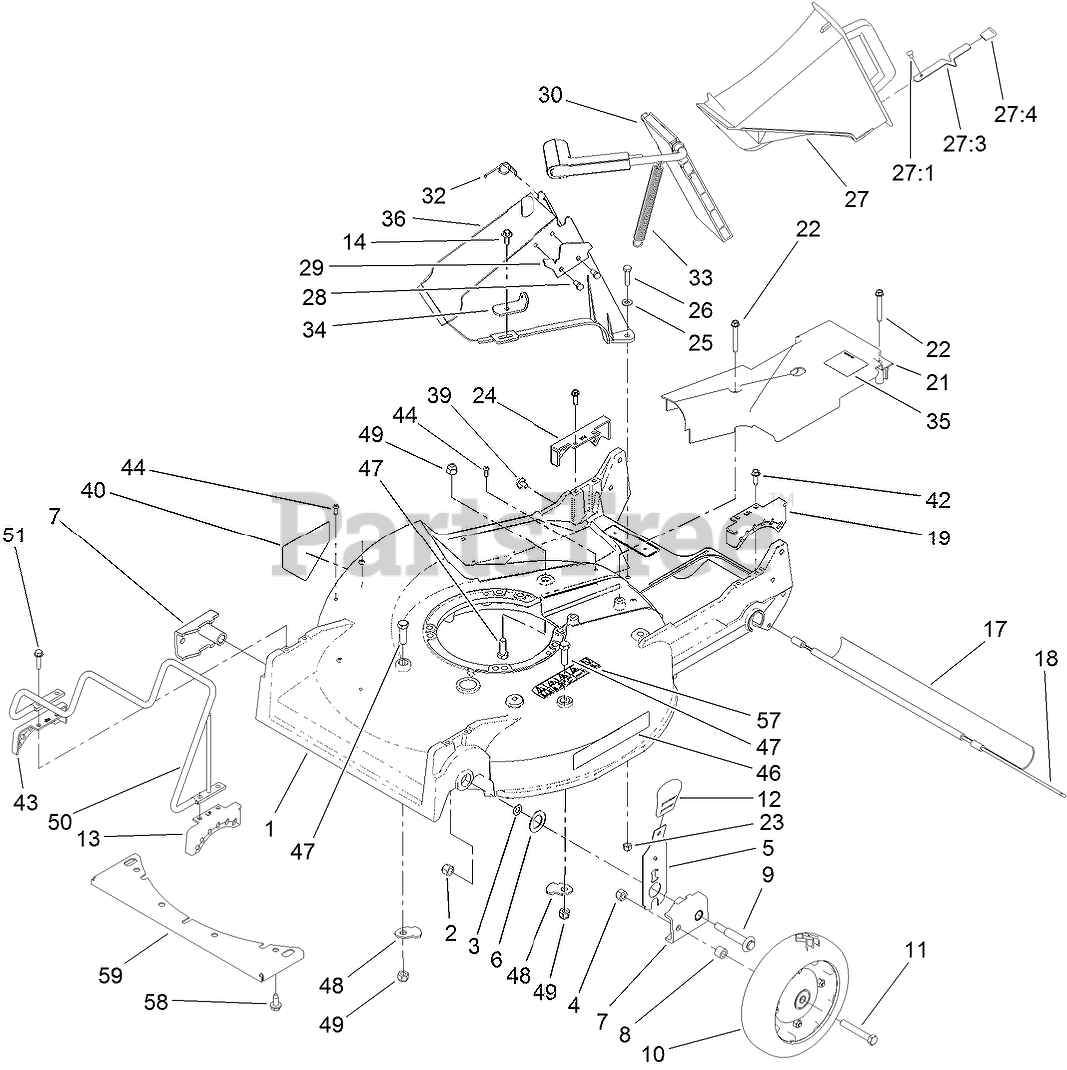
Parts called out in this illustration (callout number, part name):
1	HOUSING
2	NUT-LOCK
3	WASHER
4	NUT-LOCK, CONE
5	FRONT SPRING ARM ASM
6	WASHER-THRUST
7	ARM-PIVOT, FRONT
8	SPACER-WHEEL
9	SCREW-SHOULDER
10	WHEEL AND TIRE ASM
11	SCREW-HH
12	KNOB-HOC
13	QUADRANT-FRONT, LH
14	SCREW-HWH
17	SHIELD-TRAILING
18	ROD-SHIELD
19	QUADRANT-REAR, LH
21	COVER-BELT
22	SCREW-HWHTF
23	NUT-LOCK, NI
24	QUADRANT-REAR, RH
25	WASHER-FLAT
26	SCREW-HH
27	DISCHARGE PLUG ASM
27:1	RIVET-HEAD, FLAT
27:3	LATCH-PLUG, DISCHARGE
27:4	GRIP-LATCH
28	SCREW-PLASTITE
29	LATCH-PLATE
30	DISCHARGE DOOR ASM
32	RETAINER-DOOR
33	SPRING-DOOR
34	BRACKET-SPRING
35	DECAL-GREASE
36	TUNNEL-DISCHARGE
39	SCREW AND WASHER ASM
40	DECAL-DANGER
42	SCREW-HWHTF
43	QUADRANT-FRONT, RH
44	SCREW-PPH
47	SCREW-HH
48	SHIELD-RETAINER
49	NUT-LOCK, NI
50	GUARD-ENGINE
51	SCREW-HWHTF
57	DECAL-DANGER
58	SCREW-HWHTF
